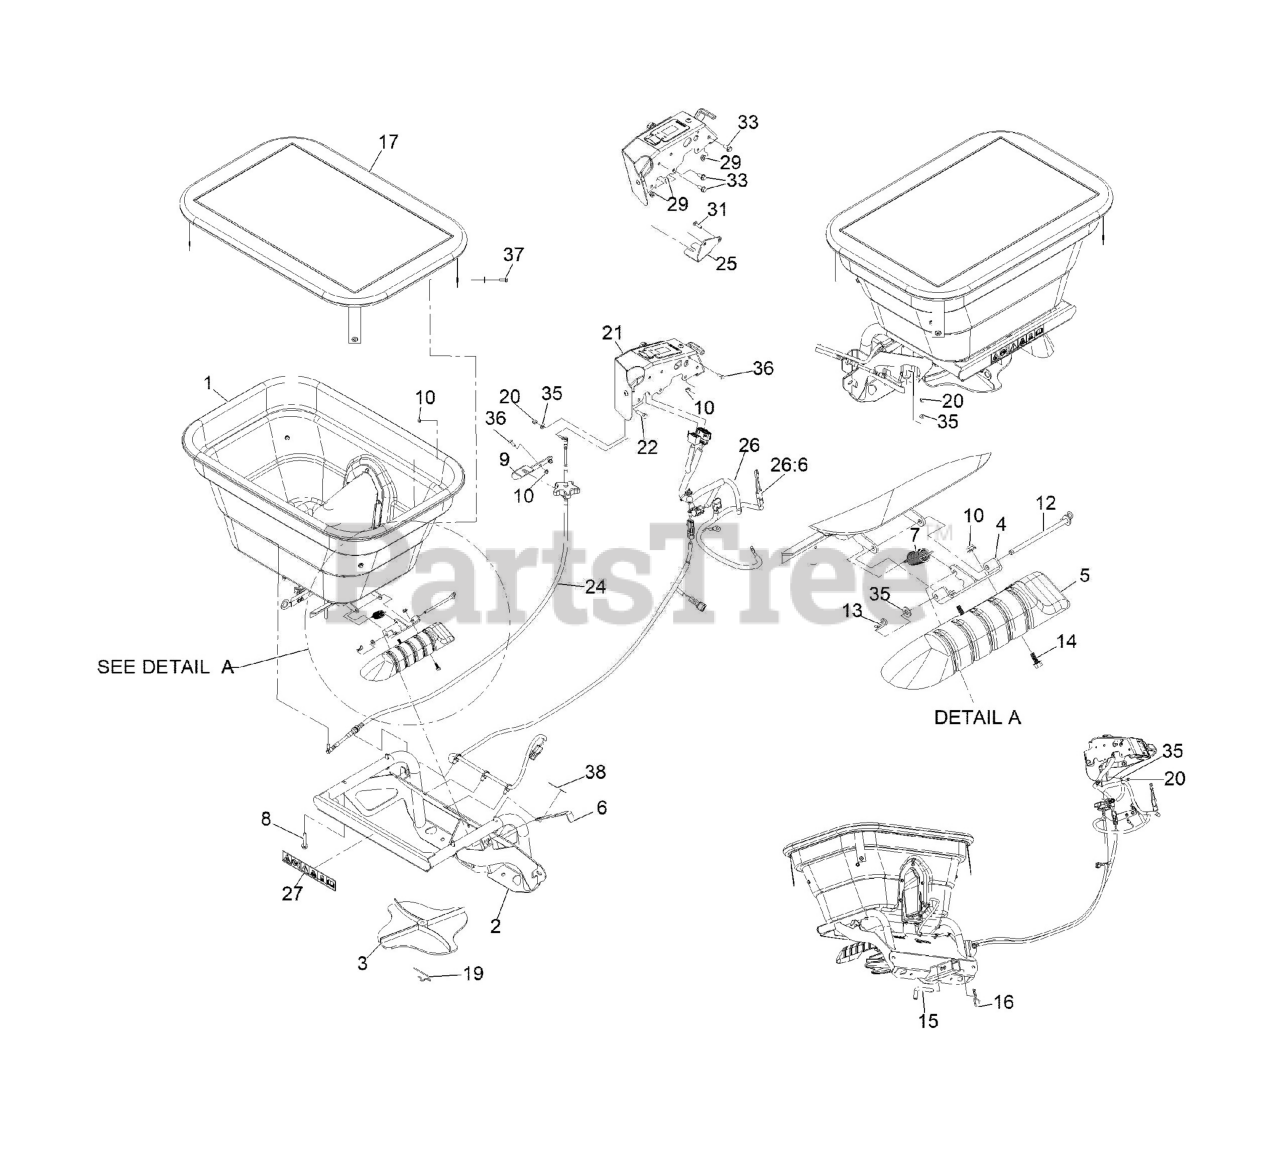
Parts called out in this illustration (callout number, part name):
1	Asy-Spreader Hopper (Exmark)
2	SPREADER HOPPER FRAME ASM
3	Spinner-Spreader
4	BRACKET-DEFLECTOR
5	DEFLECTOR
6	STRAP-ENGAGEMENT
7	Spring-Extension
8	Screw-HWH
9	BRACKET-CABLE
12	PIN-PIVOT
13	PIN-COTTER
14	SCREW-HHF
15	PIN-HITCH
16	PIN-HAIR
17	COVER-HOPPER
19	Clip-Spinner
20	NUT-LOCK
21	Spreader Controller ASM
22	SCREW-HH
24	CABLE-PUSH, PULL
25	BRACKET-CABLE
26	HARNESS
26:6	CONNECTOR
27	DECAL-DOWN, TIE
29	NUT-HF, NI
31	SCREW-CARR
33	SCREW-HHF
35	WASHER-FLAT
36	SCREW-HH
37	SCREW-HWH
38	DECAL-WARNING
